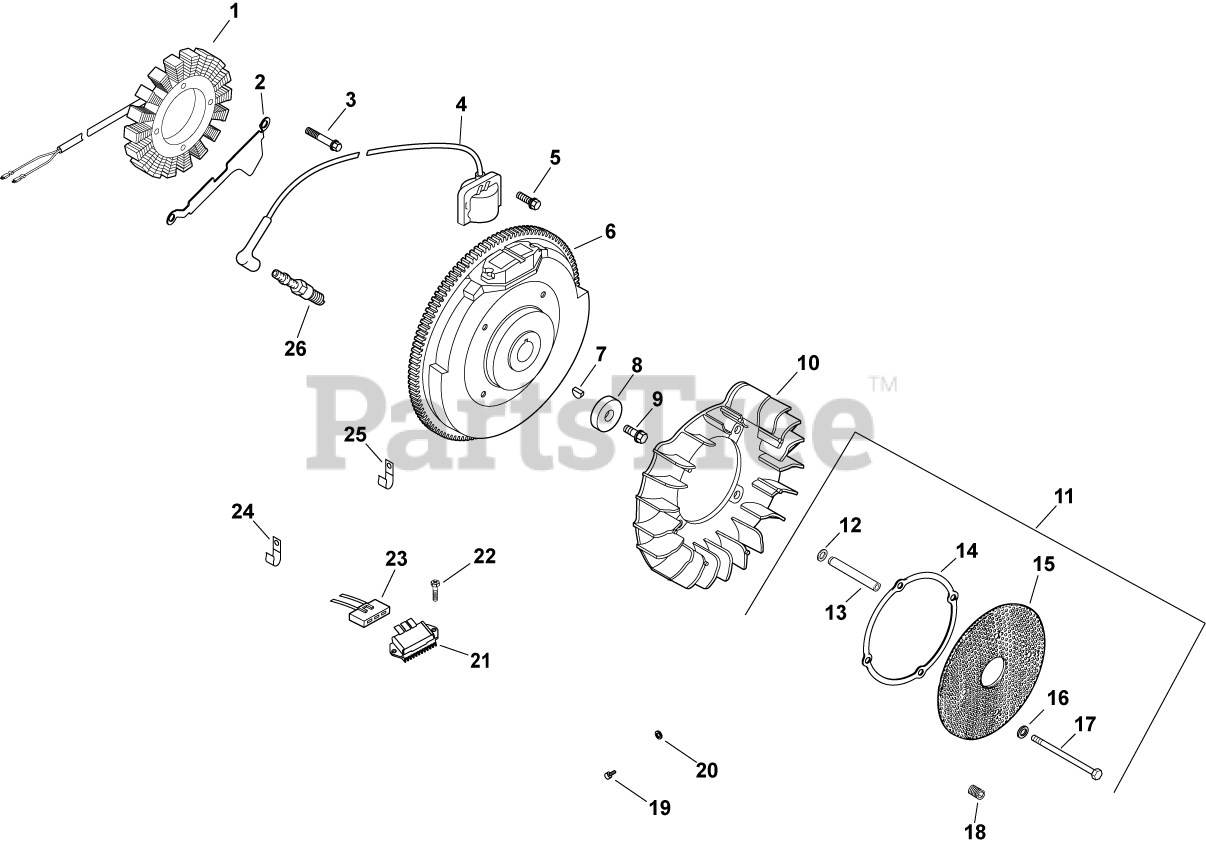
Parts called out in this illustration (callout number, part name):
1	KIT, 15 / 20 AMP STATOR
2	BRACKET, STATOR WIRE
3	SCREW, M5X0.8X25 - (#25086402S)
4	KIT, MODULE IGNTN (CDI FIXED)
5	SCREW, FLG THD FRM M5X.8X20-(#25086399S)
6	FLYWHEEL, PAINTED-USE 24 025 55-S
7	KEY, 3/16" X 5/8"
8	WASHER, FLAT 13/32"
9	SCREW, FLG M10X1.5X45 - (#25086361S)
11	KIT, CHOPPER SCREEN
12	WASHER, SPRING 10 MM
14	RING, SUPPORT USE 25 141 08-S
15	SCREEN, GRASS
16	WASHER, FLAT 1/4" (O.D. 5/8")
17	SCREW, CAP M6X1.0X99.5
18	SCREW, SKT SET #10-24X1/4"
19	SCREW, SOCKET TRUSS HD CAP
20	WASHER, FLAT 1/4" (O.D. 1/2")
21	REG/RECT-15 AMP (KM)-USE 41 403 10-S
22	SCREW, PHL HD #11-16X7/8"
23	CONNECTOR, BODY (KM)-USE 25 155 41-S
24	CLIP, TUBE & WIRING (KM)
25	CLIP, CABLE
26	PLUG, SPARK (PRO SERIES)
2417640-S	HARNESS, WIRING
2508627-S	SCREW, VALVE
2545403-S	TIE, WIRE
4103710-S	NAMEPLATE, SERVICE
24126137-S	BRACKET, GROUND STRAP USE 24 518 12-S
